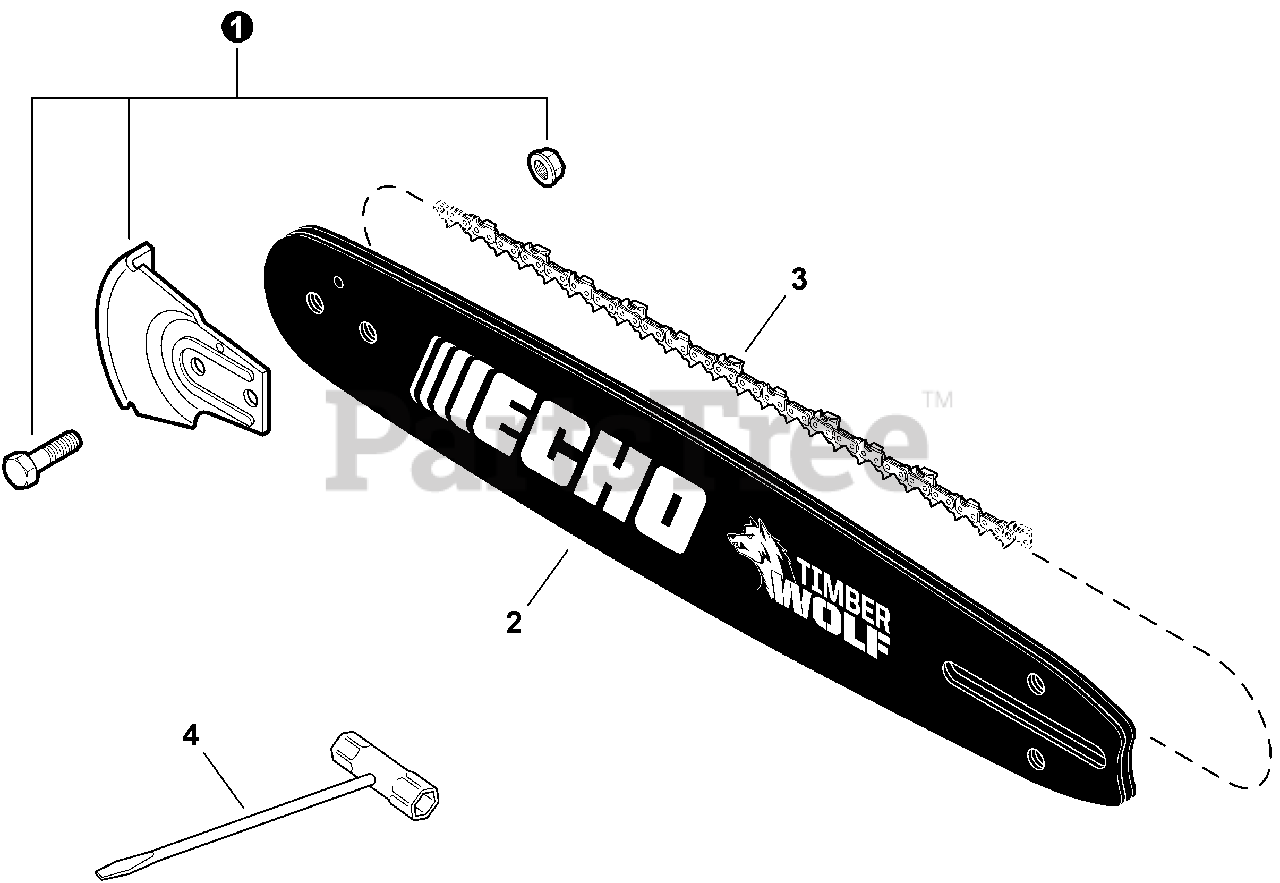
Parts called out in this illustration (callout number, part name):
1	KICK GUARD KIT
2	GUIDE BAR, 18" PROAM
2	GUIDE BAR, 20" PROAM
3	SAW CHAIN 18"
3	SAW CHAIN - 20"
4	T-WRENCH 13×19 L= 180
